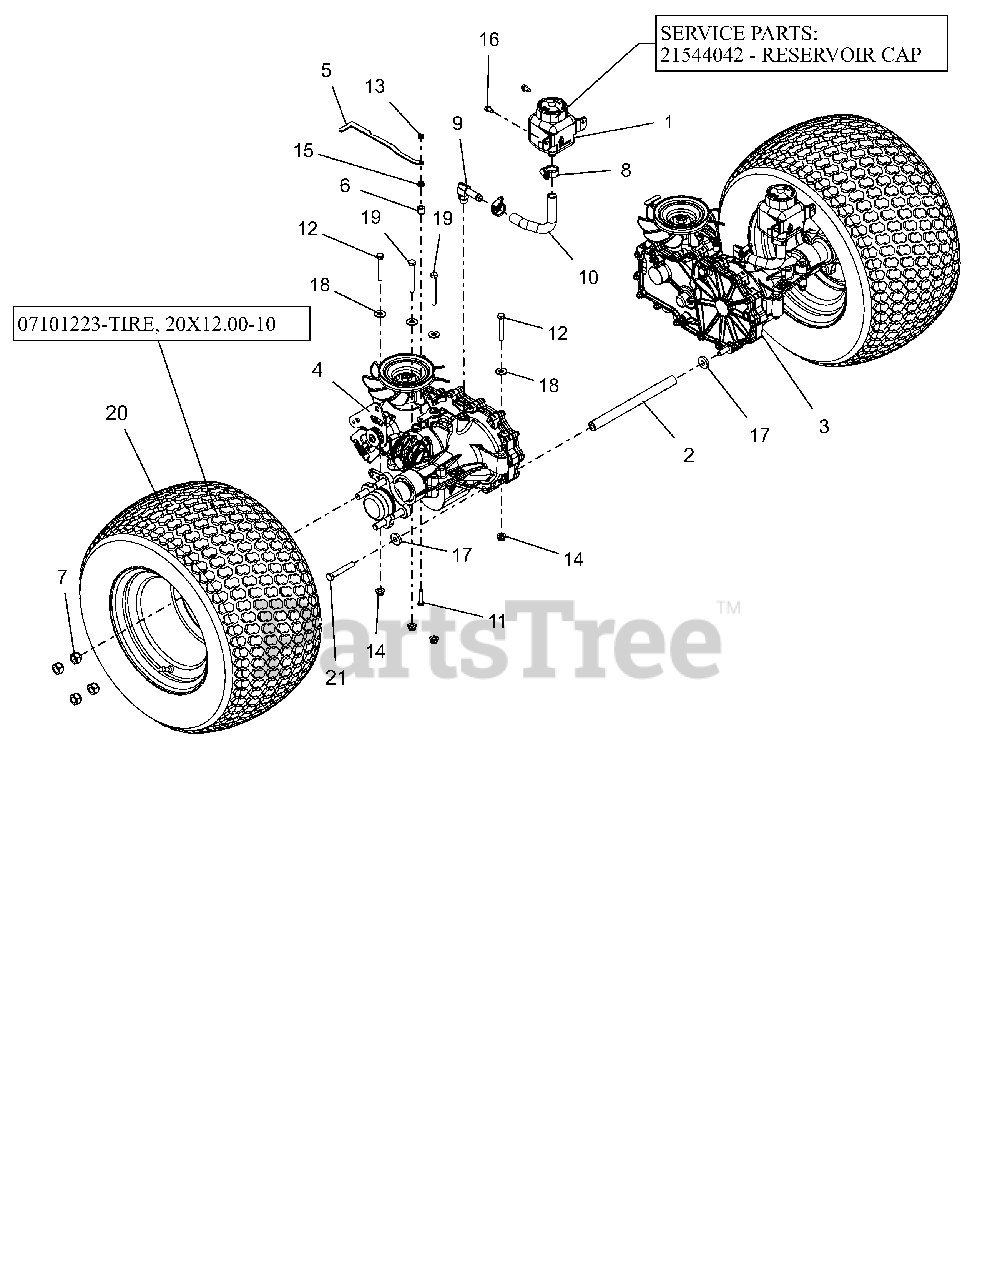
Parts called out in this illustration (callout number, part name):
1	TANK, EXPANSION
1	CAP, HYDRO RESERVOIR REPLAC.
2	ROD, TRANSAXLE BRACE 9.27
3	TRANSAXLE,ZT2800 LH
4	TRANSAXLE,ZT2800 RH
5	BRKT, DUMP VALVE
6	BSHG-SLV .265X.500X.500
7	WHEEL NUT .500-20 YZ
8	CLAMP,.88 DIA. HOSE
9	FITTING, HYD (90 DEG)
10	HOSE, FORMED LH XL
11	@BLT-HEX .25-20X1.25 GR5 YWZC
12	@BLT-HEX .31-18X2.25 GR5 YWZC
13	NUT-LK-CTR JAM .25-20 YWZC
14	@NUT-LK-NYL-FLG .31-18 YWZC
15	@NUT-SPNLK-FLG .25-20 YWZC
16	SCR-TAP .25-20X.50 HWH TR YWZ
17	WSHR-FL-STL .406X1.00X.188 YWZ
18	@WSHR-FL-STL.38X.875X.083 YWZC
19	@BLT-HEX .31-18X2.75 GR5 YWZC
20	ASM, WHL/TIRE 20X12.00-10
20	TIRE, 20X12.00-10 (OTR)
21	@BLT-HEX .38-16X2.50 GR5 YWZC
